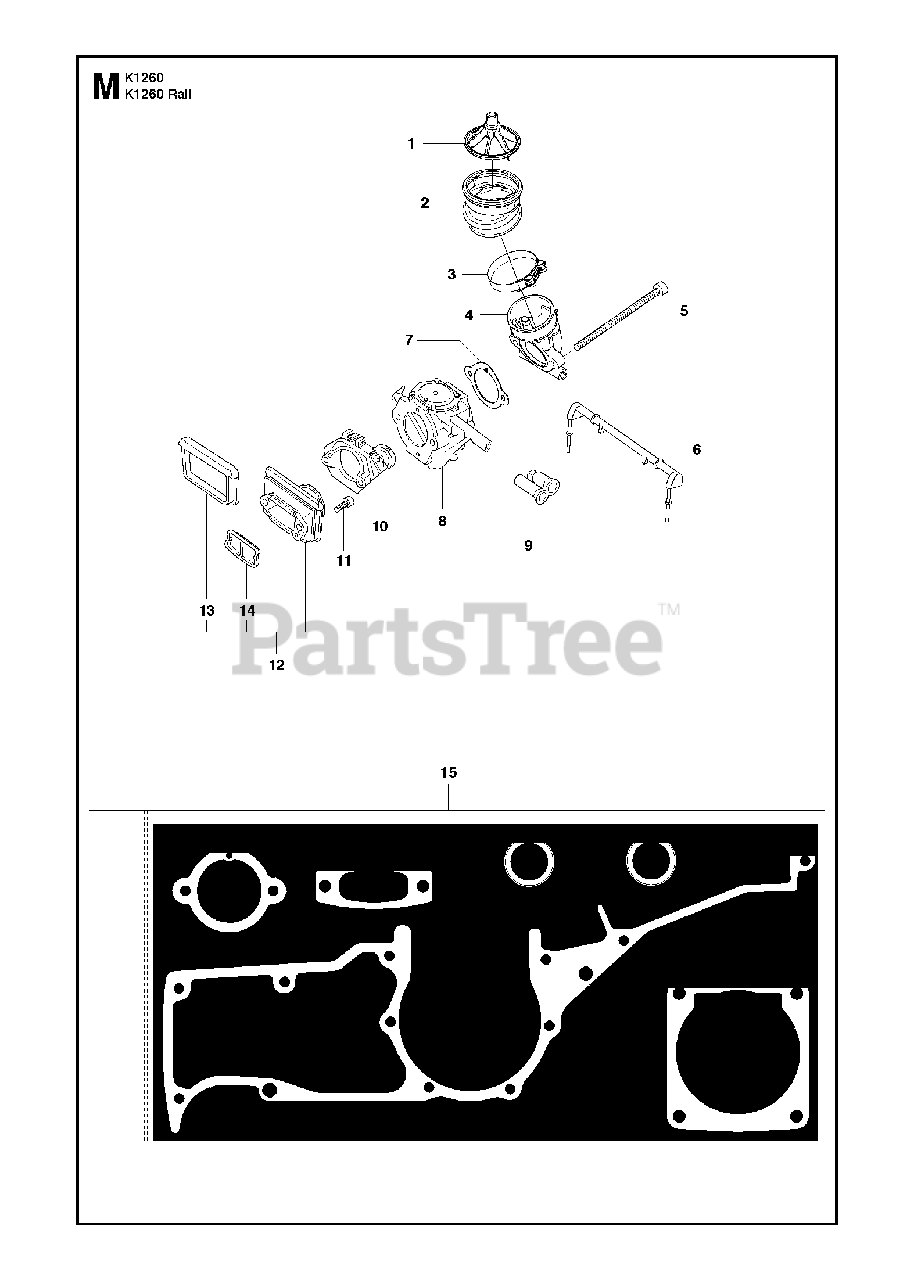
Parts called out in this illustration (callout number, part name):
2	BELLOWS
3	HOSE CLAMP
5	SCREW ITXSCT
7	GASKET
9	CHISEL GUIDE
11	SCREW ITXSCM
12	FLANGEIncl. 13 - 14
15	GASKET KITIncl. 7, 16 - 19
17	SEALING RING
